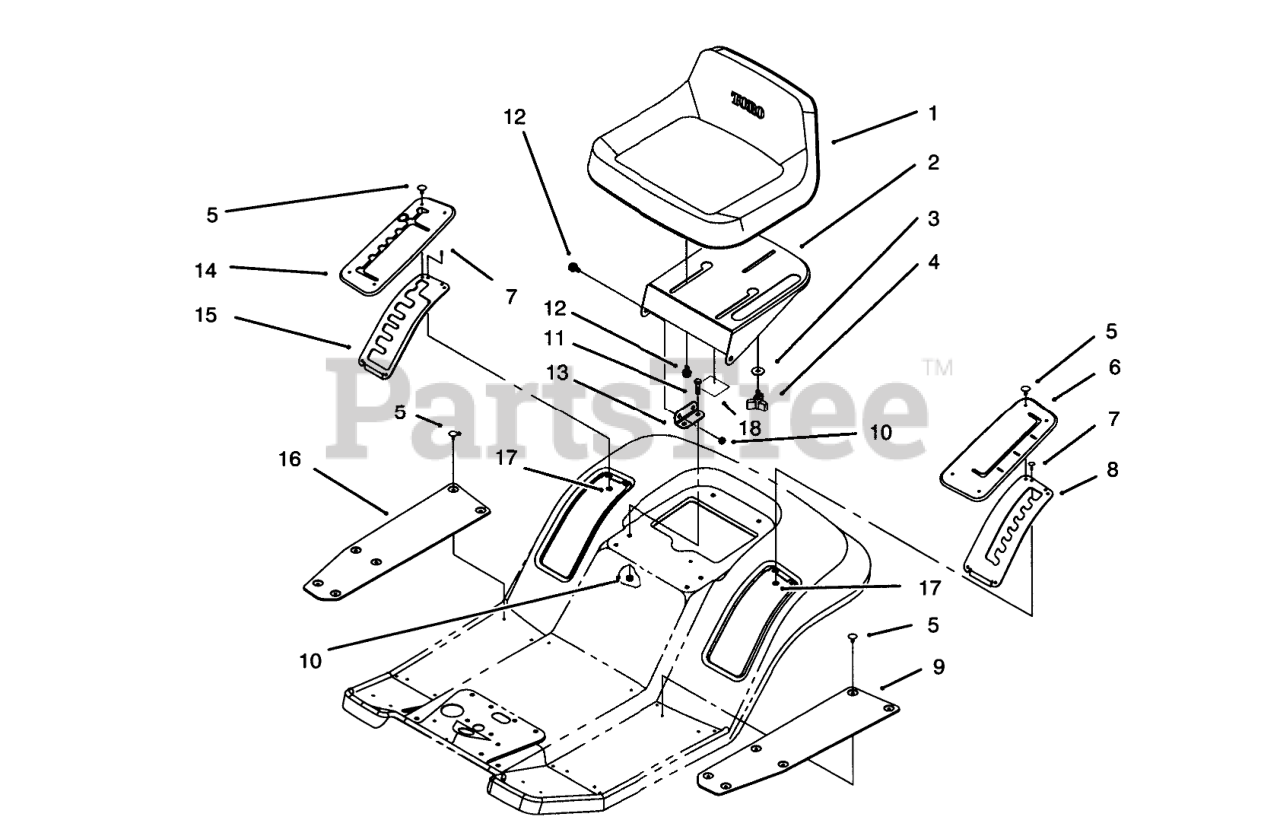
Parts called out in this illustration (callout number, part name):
1	SEAT
2	Support-Seat
3	WASHER-PIVOT
5	FASTENER-PANEL
6	COVER-HOC
7	RIVET-BLIND
8	Gate-H.O.C.
9	MAT-FOOT, LH
10	NUT-LOCK, NI
11	SCREW-HH
12	BOLT-SHOULDER
13	Bracket-Seat Hinge
14	COVER-SHIFT
15	Gate-Shift
16	MAT-FOOT, RH
17	WASHER-PLAIN
18	DECAL-EUROPE
